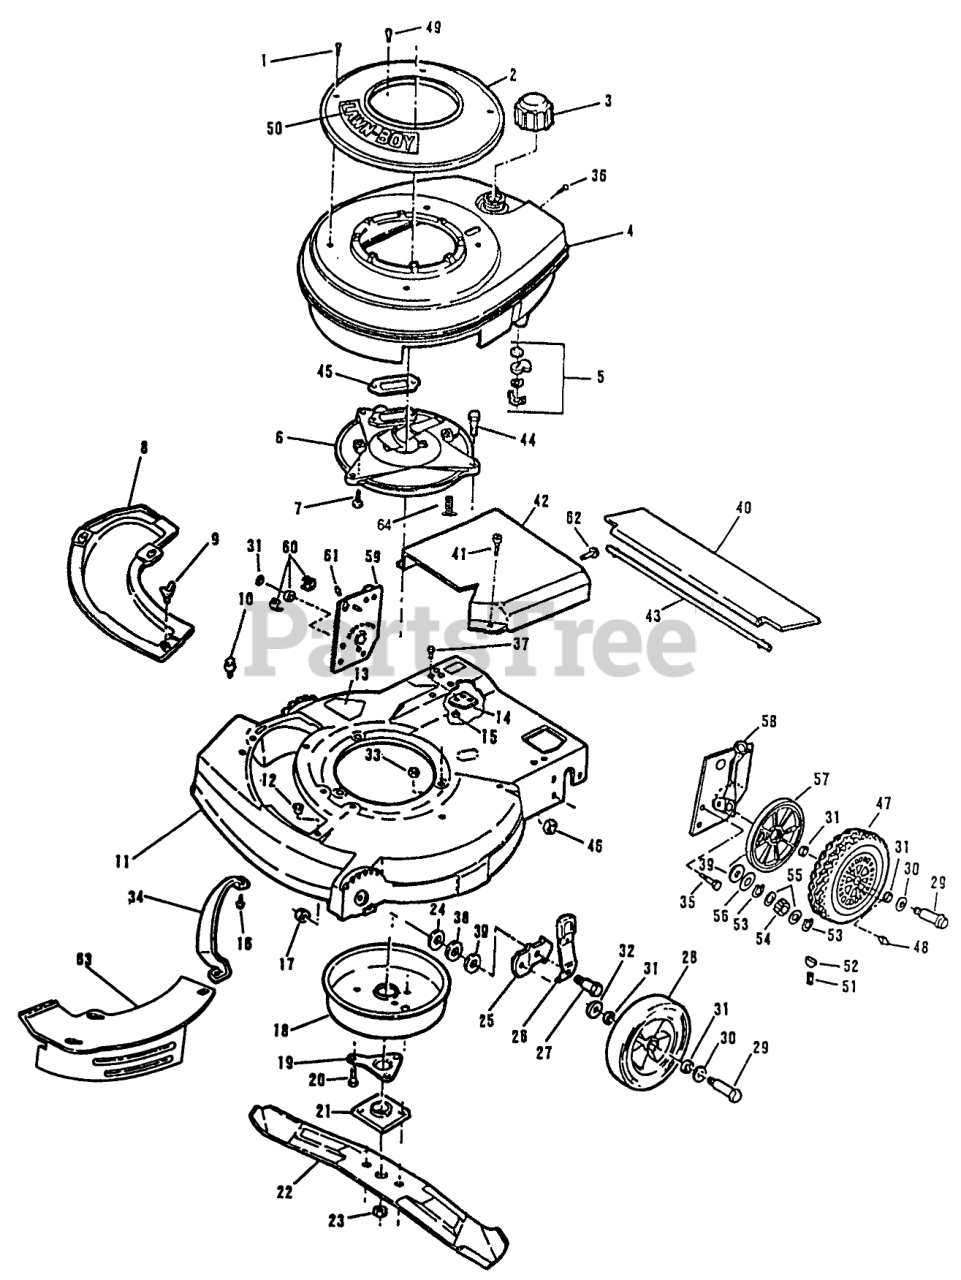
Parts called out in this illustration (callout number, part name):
1	SCREW S
2	STARTER BASE&NUTB
3	FUEL CAP & INSERT
4	Shroud-Engine
5	SHUT OFF VALVE KIT
6	PLATE F
7	SCREW V
8	CoverPlate
9	WING SCREW LAWRE
10	Bolt
11	Housing Assembly
12	Grommet
13	Decal
14	BOLSTER
15	LOCKNUT E
16	Screw
17	Nut
18	MUFFLER COVER F
19	SUPPORT F
20	SCREW
21	PLATE AND COLLAR ASM
22	21" Blade
23	NUT-BLADE
24	WASHER
25	Bracket
26	SPRING ARM ASM
27	BOLT
28	WHEEL&TIRE 6"
29	BOLT WHEEL
30	WASHER-PLAIN
31	WASHER
32	WASHER WROUGHT
33	NUT-LOCK F
34	BAR-TOE
35	Screw
36	SCREW S
37	Screw
38	WASHER
39	WASHER
40	SHIELD-TRAILING
41	SCREW SEMS TRM HEX HD
42	COVER DRIVE PL
43	ROD-TRAILING SHIELD
44	SCREW-HH
45	Gasket
46	NUT-LOCK F
47	WHEEL AY
48	FITTING LINCOLN
49	SCREW SEMS SM
50	APPLIQUE
51	SPRING
52	KEY
53	RET RING
54	PINION BROCKWAY
55	SPACER/GR ALGHNY
56	THRUST WASHER
57	W/COVER WHITE PL
58	HEIGHT ADJ AY-LH
59	HEIGHT ADJ AY-RH
60	REAR AXLE BEARING
61	FITTING LINCOLN
62	SCREW
63	Mulcher Plate Kit w/Decal
64	SCREW-SEMS F
